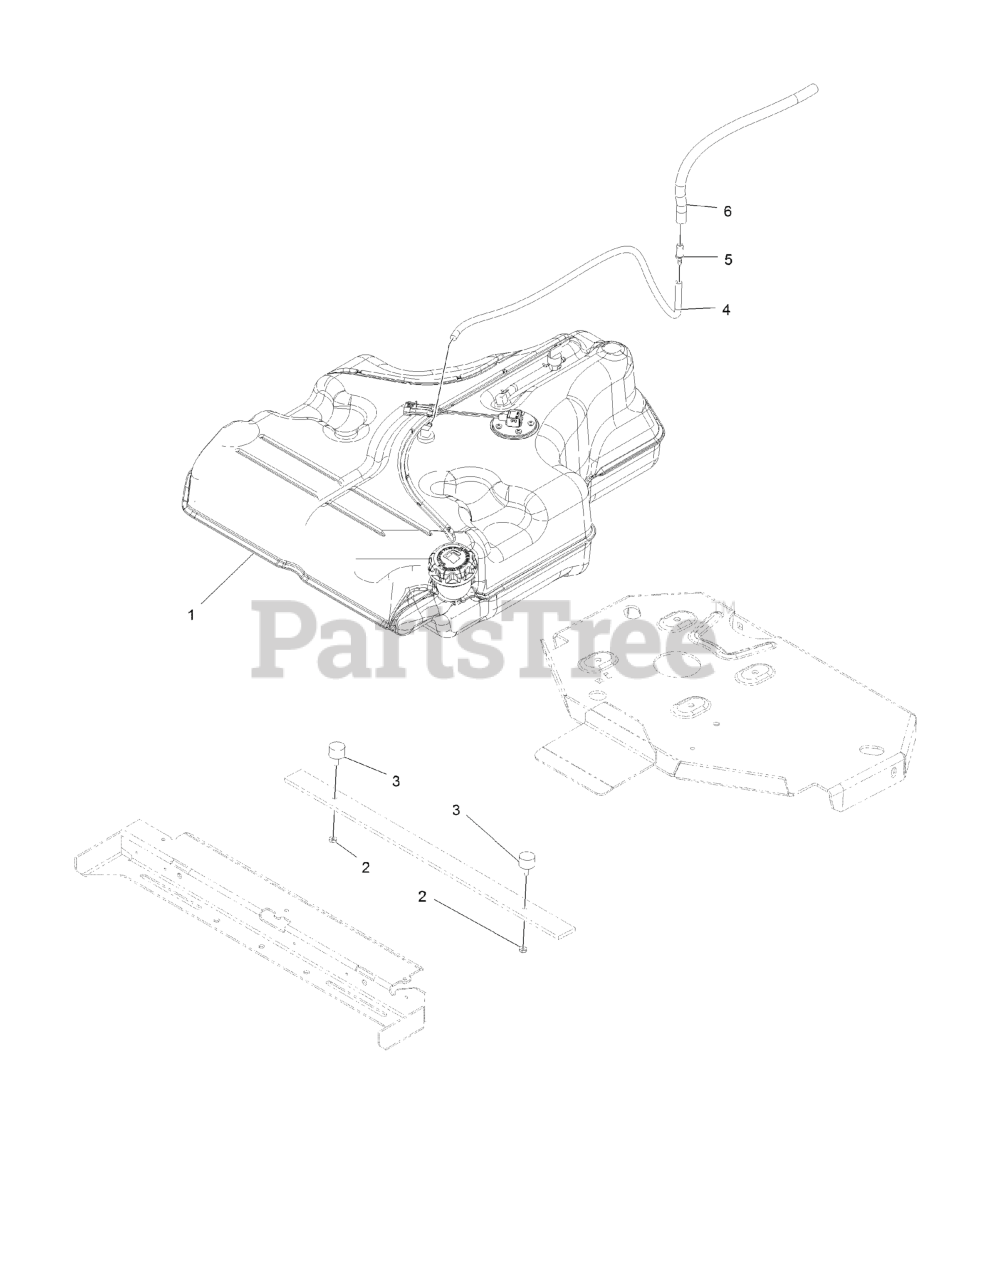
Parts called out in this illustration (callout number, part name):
1	FUEL TANK ASM
2	NUT-JAM
4	HOSE-FUEL
5	FITTING-STRAIGHT
6	HOSE-FUEL
